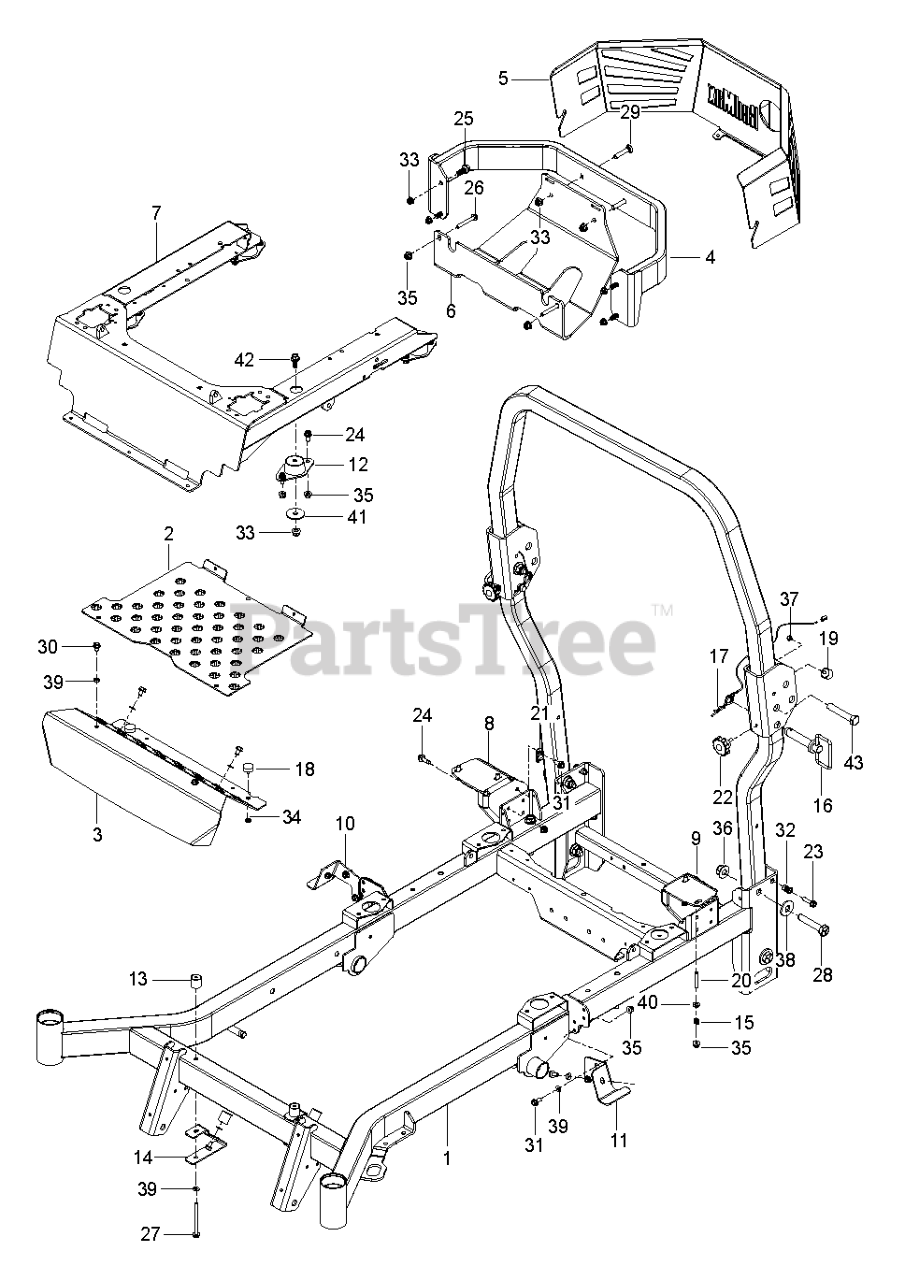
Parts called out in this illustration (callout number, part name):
1	FRAME W/DECALS REDMAX 72
2	PLATE FLOOR PAN SNAPPER RED X6
3	PLATE.FOOT.REST.BLACK
4	BUMPER REAR LONG SNAPPER RED X
5	GUARD REAR SNAPPER RED X672
6	PLATE, SKID, BLACK
7	FRAME SEAT MOUNT SNAPPER RED X
8	MOUNT, RT TANK, BLK
9	MOUNT, LT TANK, BLK
10	BRACKET TANK.FT.RT BLACK MS-43
11	MOUNT, TANK, LT-BLK
12	MOUNT, ISO
13	MOUNT, F/F INSERT
14	BRACKET, REST MOUNT
16	PIN.ROPS.W/HANDLE
17	PIN.HAIR.DOUBLE.LOOP.W/LANYARD
18	BUMPER, 1/4-20 STUD, 1/4
19	BUMPER, MALE STUD, 1/4-20
20	STUD, 5/16C
21	DOUBLE TUBE CLAMP
22	KNOB.5/16-18X1"BLACK
23	HHFS 5/16-18 X 1.25 TPBLT GD 5
24	HHFS 5/16-18 X 3/4
25	HHFS 3/8-16 X 1 GRD 5 ZD
26	HHFS 5/16-18 X 2.25 GD 5
27	HHFS 5/16-18 X 3 3/4
28	5/8-11 X 3-1/2 HHB GRADE 5
29	RHSNB 3/8C X 2
30	SCR 5/16-18 X 1/2 SELFTAP ZN
31	SCREW
32	NUTSERT 5/16-18 THICK GRIP
33	NUT 3/8-16 HEX FLG NYLOC ZD
34	JAM NUT 1/4C (2 2 PW01)
35	5/16-18 NYLOC FLANGE NUT
36	NUT 5/8-11 FLG NYLOC ZD
37	RP_NUT 1/4-20 NYLOC
38	WASHER, 5/8 FLAT
39	WASH 5/16 DISC SPRING ZD
40	WASHER
41	WASHER, 3/8 SPEC
42	HHFS 3/8-16 X 1 GRD 5 ZD
43	BOLT.HEXAG.5/8-11X4-1/4.G5.ZPY
